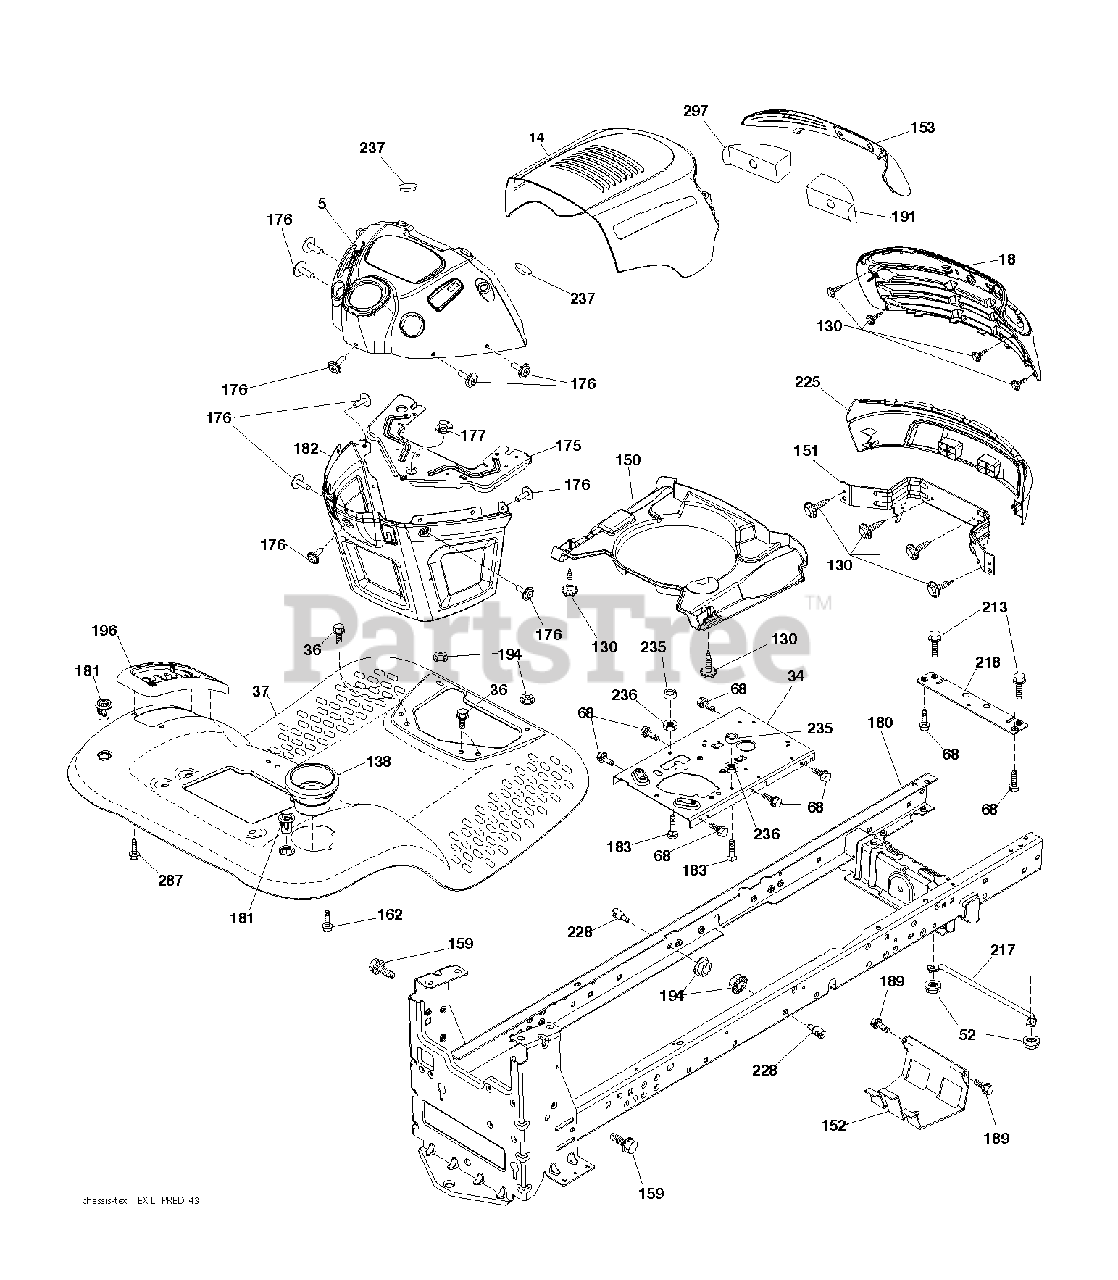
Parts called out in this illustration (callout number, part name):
5	DASH.PREDLT.CC.ICY.CK.N/SRV.BL
14	HOOD.PREDATR.LT.U-FRM.TPVNT428
18	GRILLE.SVC.BASE.PREDATOR.LT428
34	PLATE.ENGINE.WELDED.CHASSIS
36	SCREW 5/16"
37	FENDER.TLT.W/CPH.428
52	LOCKNUT
130	SCREW.#10 X 0.750.BOS THREAD
138	CUPHOLDER.TL.TEX.BLACK
150	DUCT.AIR.TOP.VENT.PREDATOR.LT
151	BRACKET.PIVOT.ALPHA.LT
152	SHIELD BROWNING
153	LENS.PREDATOR.LT.
159	SCREW, 3/8-16X3/4
162	SCREW.HI-LO.CONSOLE
176	SCREW.#10-24X5/8.RN.QU
177	BUSHING STEERING
180	CHASSIS
181	FEND/FTRST.PCH.CPH.NFW
182	DASH.LWER.PREDATOR/HUSQ.LT
183	BOLT.5/16-18X1-1/4 FULL THD
189	SCREW
191	INSERT.REFLECT.PREDATOR.LT.RH
194	NUT LOCK HEX FLANGE 5/16-18
213	BOLT
217	ROD.PIVOT.HOOD
218	X-PIECE.HOOD.STOP.NON/
228	STUD.FASTNER.W/ANTI-ROTATE
235	SPACER FENDER
236	NUT.CENTERLOCK.5/16-
237	PLUG.MOUNT.CARGO.BLK
297	REFLECTOR.INSERT.PRED.LH.LT
